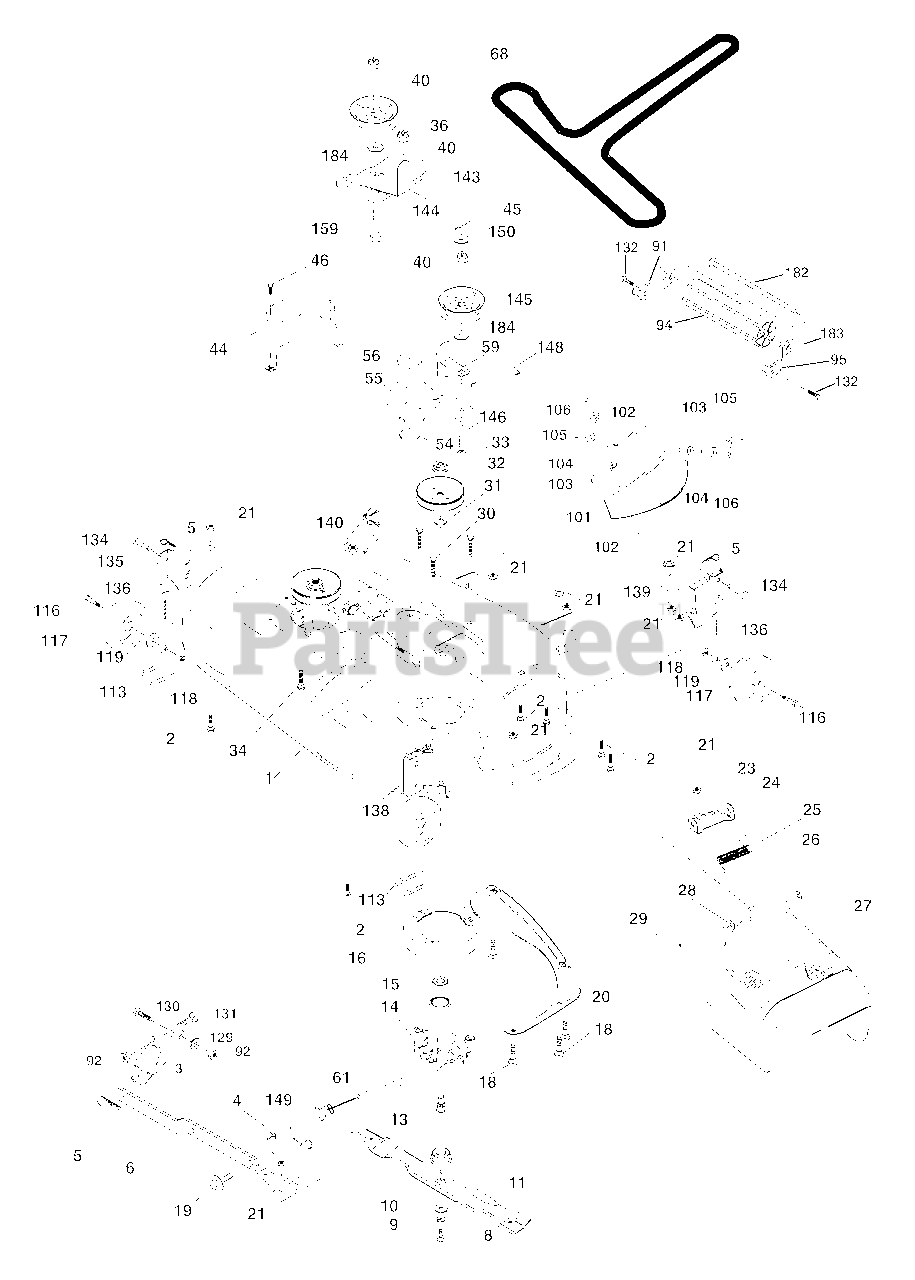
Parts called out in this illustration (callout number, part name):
1	Mower Housing
2	Bolt
3	Bracket Assembly,Sway Bar, Front
4	Bracket Sway Bar 38/42"
5	Retainer Spring
6	Bar Sway Deck
8	Bolt, Hex 3/8-24 x 1.25 Gr. 8
9	Washer, Lock
10	Washer, Hardened
11	Blade, 42" Mulching STD
11	Blade, 42" Mulching Premium
11	Blade, 42" Hi-Lift
13	Shaft Assembly, Mandrel, Vented
14	Housing, Mandrel, Vented
15	Bearing, Ball, Mandrel
16	Stripper, Mower Deck
18	Bolt, Carriage 5/16-18 x 5/8
19	Bolt, Shoulder
20	Baffle, Vortex
21	Nut, Crownlock 5/16-18 unc
23	Bracket, Deflector
24	Cap, Sleeve
25	Spring, Torsion, Deflector
26	Nut, Push
27	Shield, Deflector
28	Washer 11/32 x 5/8 x 16 Ga.
29	Rod, Hinge
30	Screw Thdrol Rolling Wsh Hd
31	Washer, Spacer
32	Pulley, Mandrel
33	Nut, Toplock, Flanged
34	Bolt
36	Pulley, Idler, Flat
37	Washer 13/32 x 13/16 x 16 Ga.
40	Nut, Lock 3/8-16 unc
44	Guard, Mandrel, L.H.
45	Retainer
46	Screw, Thd. Roll 1/4-20 x 5/8
54	Washer, Hardened
55	Arm, Idler
56	Spacer, Retainer
59	Guard, Tuv Idler
61	Spring Ext Elect Clutch
68	V-Belt
91	Bracket Roller Nose LH
92	Locknut, Hex W/Wsh 3/8-16 unc
94	Roller Nose
95	Bracket Roller Nose RH
101	Cover Mulching 42" Black
102	Screw Truss Hd Phil10-24 x 5/8
103	Washer #10
104	Washer Lock
105	Latch Asm Bagger
106	Nut Weld
113	Screw 5/16-18
116	Bolt, Shoulder
117	Wheel, Gauge
118	Nut, Crownlock 3/8-1
119	Washer 13/32 x 7/8 x 14 Ga.
129	Washer 13/32 x 13/16 x 12 Ga.
130	Bolt, Fin Hex 3/8-16 unc x 1Gr. 5
131	Bolt Rdhd Sqnk 3/8-16 unc x 1
132	Screw 3/8-16 x 3/4
134	Pin Head Rivet
135	Bracket Asm. Wheel Gauge Rear LH
136	Bar Adj. Gauge Wheel
138	Bracket Asm. Wheel Gauge Rear RH
139	Bracket Asm. Wheel Gauge Front RH
140	Bracket Asm. Wheel Gauge Front LH
143	Bracket Arm Idler 42"
144	Keeper Belt 42" Clutch Cable
145	Pulley Idler Flat
146	Bolt Carraige Idler
148	Spring Return Idler
149	Retainer Spring Yellow Zinc
150	Washer 9/32 x 3/4 x 10 Ga.
159	Bolt Rdhd Sqn 3/8-16 unc x 1-3/4
182	Rod Roller Nose
183	Retainer Spring
184	Washer 3/8
